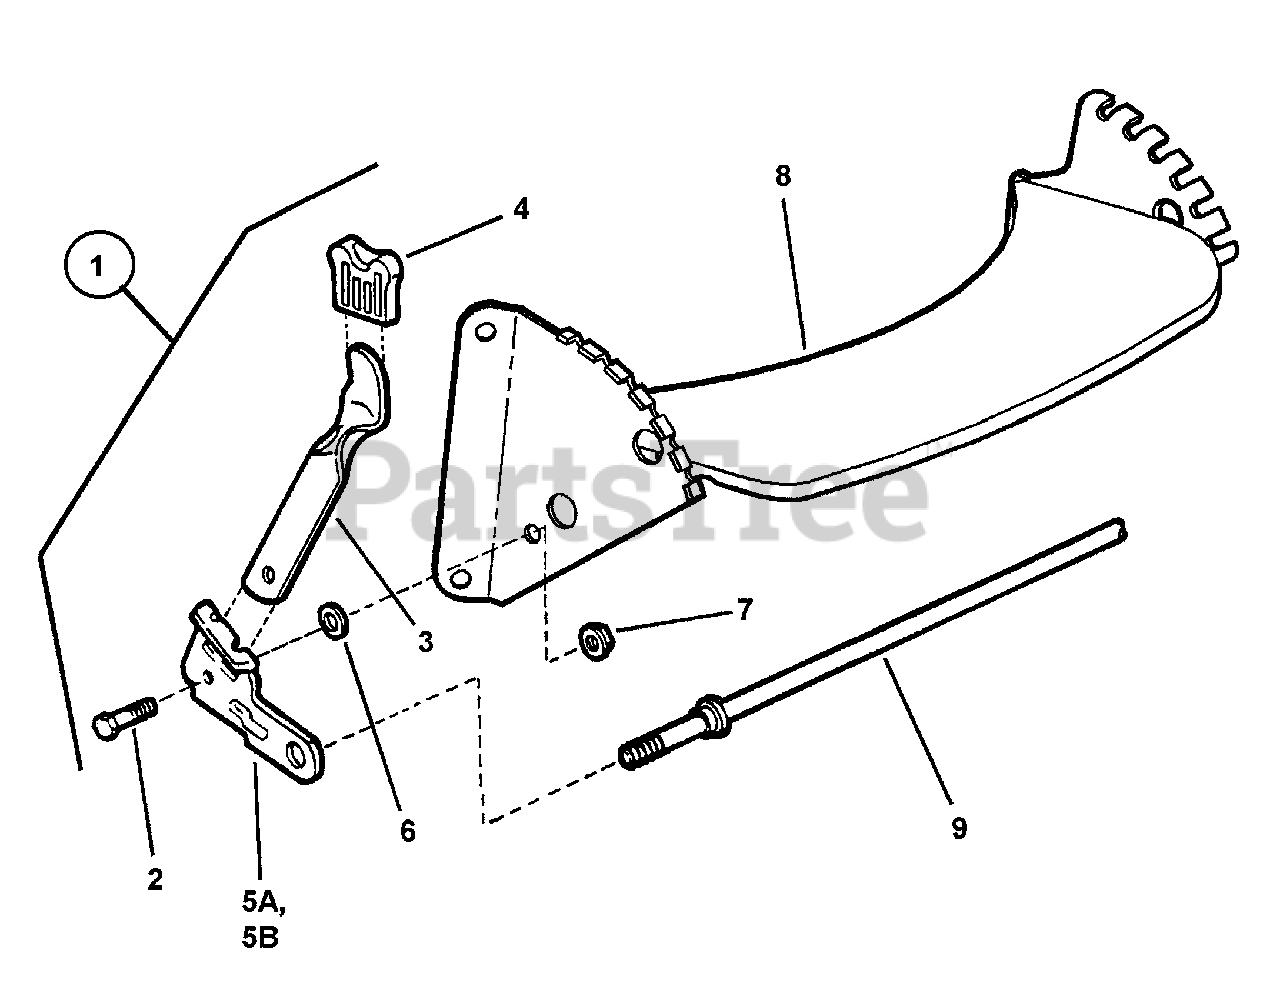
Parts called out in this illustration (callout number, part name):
1	ASSEMBLY, Arm Left Wheel
2	BOLT, 5/16-18 x 3/4" Shoulder
3	LATCH, Height
4	GRIP, Latch
5A	ARM, Left Wheel
5B	ARM, Right Wheel
6	RETAINER, 5/16 Bolt
7	NUT, 5/16-18 Hex Flange
8	BRACKET, Front Wheel
9	AXLE
